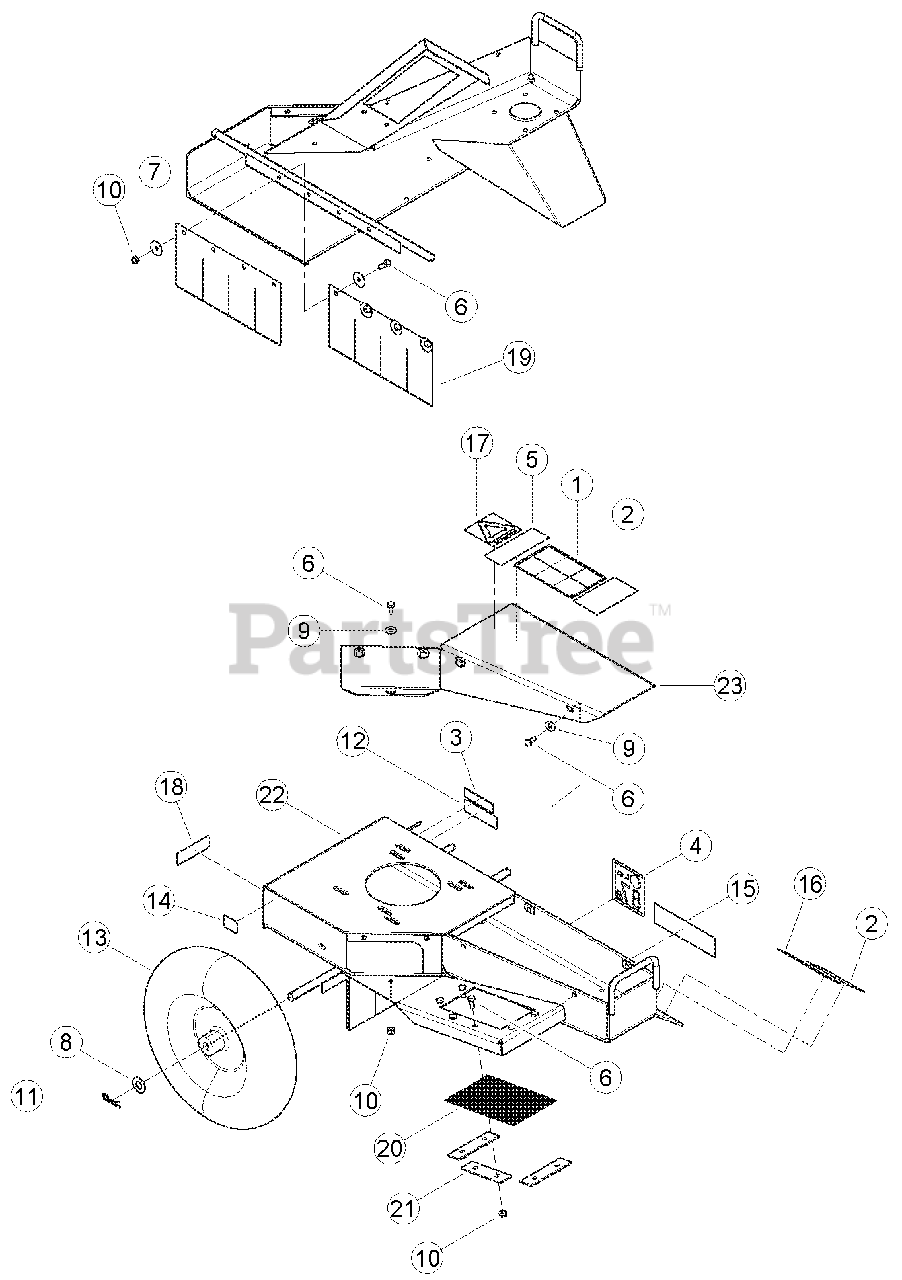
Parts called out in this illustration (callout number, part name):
1	DECAL, OPERATING INSTRUCTIONS ISO
2	DECAL, GRINDER DANGER
3	DECAL, STUMPGRINDER INFO
4	DECAL, 87 DB
5	DECAL, MULTILINGUAL MANUAL
6	BOLT, 5/16 X 3/4 HEX HD GR5 ZP
7	WASHER, 5/16 FENDER ZP
8	WASHER, 5/8 SAE FLAT ZP
9	WASHER, 5/16 FLAT ZP
10	NUT, 5/16 NE NYLOCK ZP
11	HAIRPIN CLIP ZP #203
12	DECAL, SERIAL NUMBER
13	TIRE, 480/400 X 8 WHEELBARROW
14	DECAL, CE APPROVAL
15	DECAL, ECHO BEARCAT 6.82 X 1.90
16	DECAL, MODEL SG340
17	DECAL, SMALL RECLAIM IT
18	DECAL, ATLANTIC BRIDGE LTD INFO
19	MUD FLAP, STUMP GRINDER
20	DEBRIS SCREEN, STUMP GRINDER
21	SCREEN CLAMP, STUMP GRINDER
22	WELDMENT, STUMP GRINDER FRAME
23	COVER, TOP STUMP GRINDER
